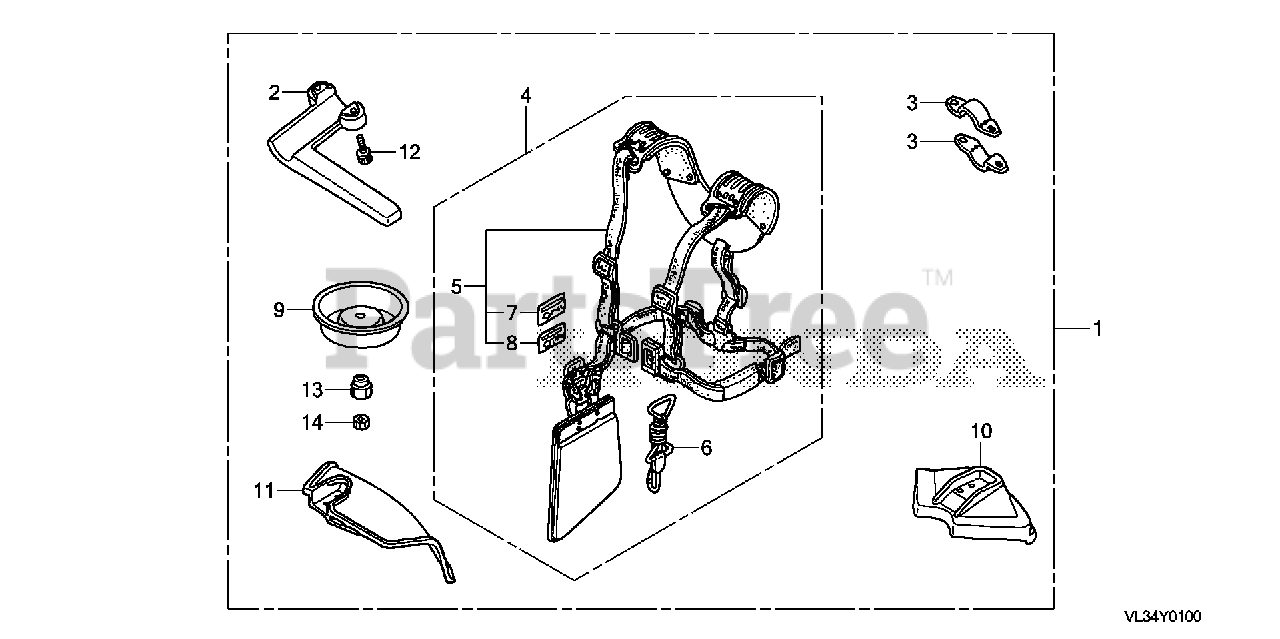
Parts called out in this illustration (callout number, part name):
1	BARRIER KIT
2	BAR, LOOP HANDLE
3	HOLDER, LOOP HANDLE
4	BELT ASSY., SHOULDER
5	BELT, SHOULDER
6	HOOK, SHOULDER BELT
7	MARK, QUICK RELEASE (E)
8	MARK, QUICK RELEASE (F)
9	COVER, NUT
10	DEFLECTOR, GRASS
11	DEFLECTOR, GRASS
12	BOLT, SOCKET (6X18)
13	NUT, LOCK (10MM)
14	NUT, HEX. (6MM)
